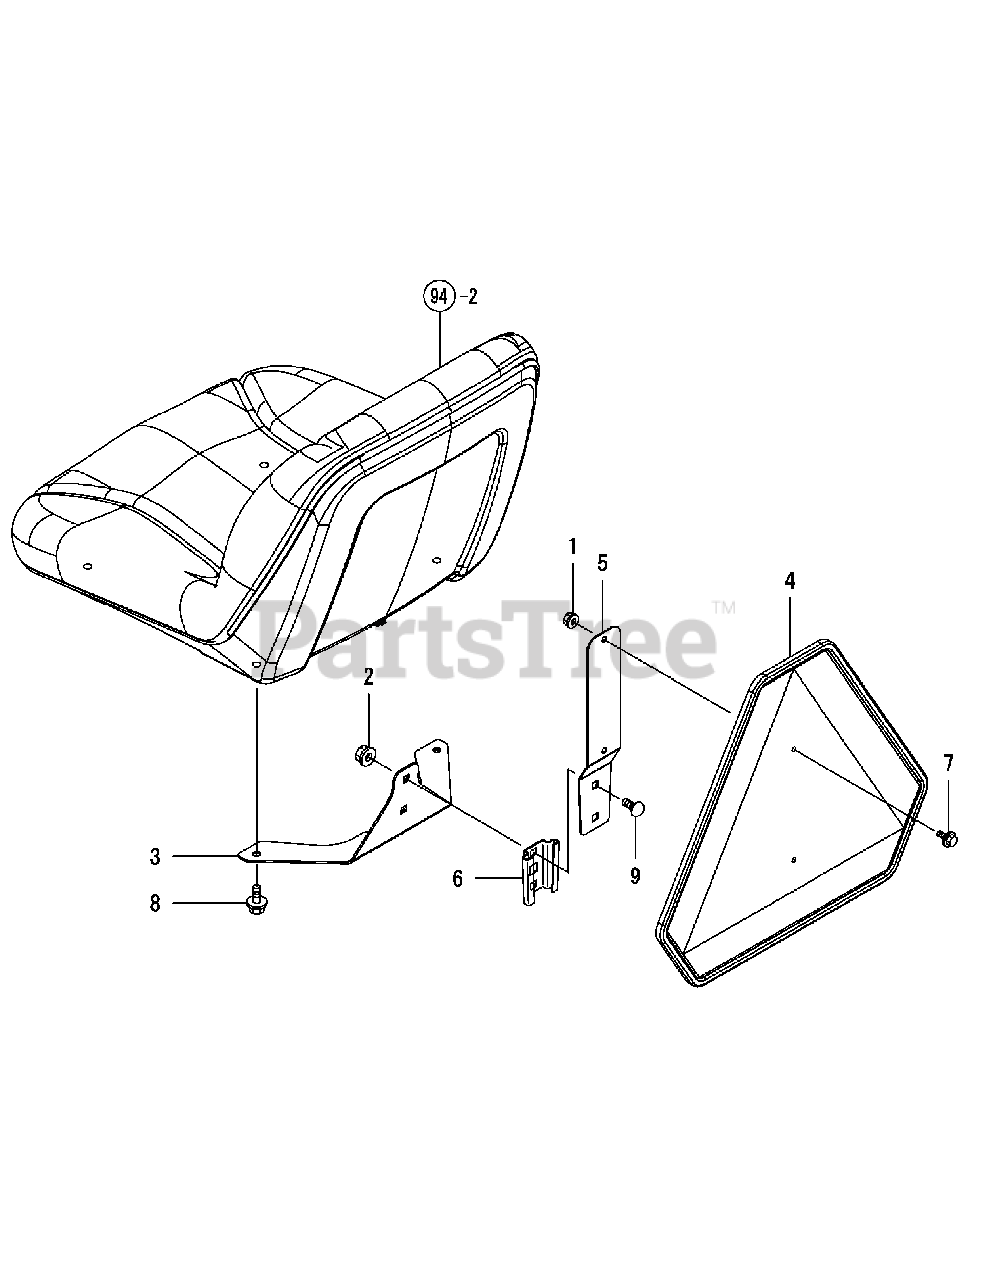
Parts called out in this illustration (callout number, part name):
1	NUT W/WASHER 6
2	NUT W/WASHER 8
4	EMBLEM, SMV ASSEMBLEY
7	BOLT M 6X 16 PLATED
8	BOLT M 8X 16 PLATED
